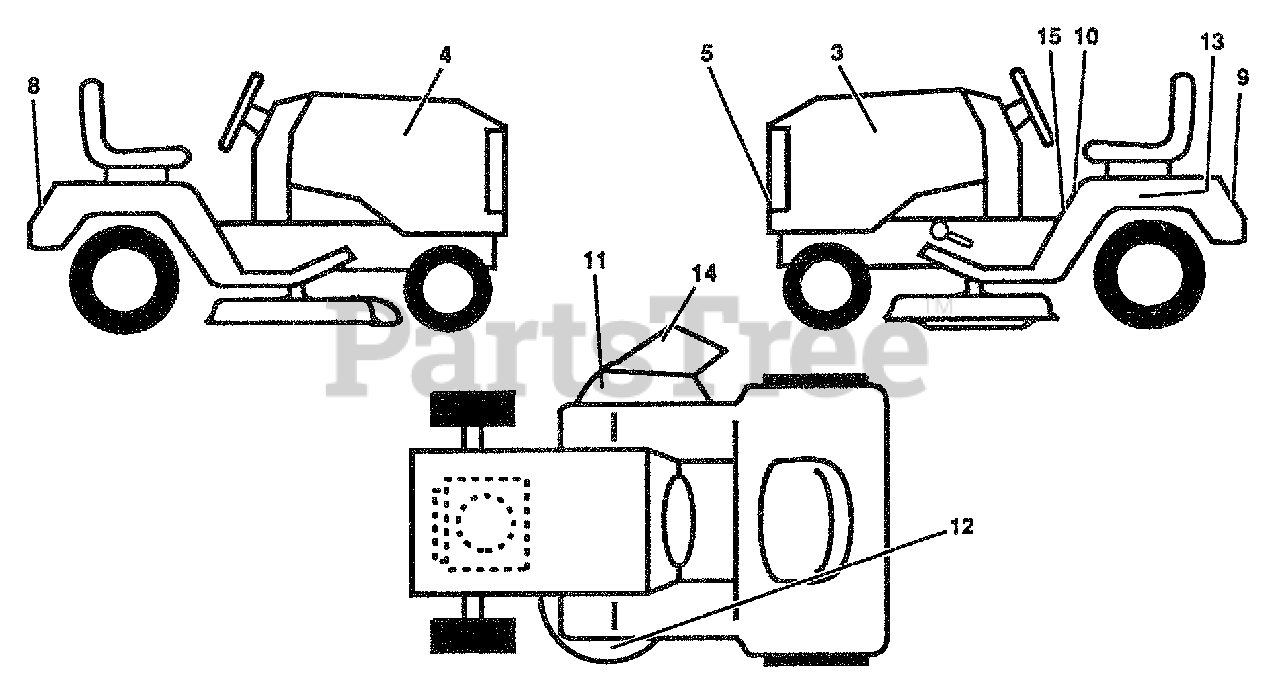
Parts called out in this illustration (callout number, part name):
3	Decal, Hood, L.H.
4	Decal, Hood, R.H.
5	Decal, Logo, Grill
8	Decal, Logo, Fender
10	Decal Caution Fender
11	Decal, Warning, Cut Finger, (Swedish/Danish/Finnish/Norwegian)
11	Decal, Warning, Cut Finger, (English/French/German/Dutch)
11	Decal, Warning, Cut Finger, (Spanish/Italian)
12	Decal, Rotating Blades, (Swedish/Danish/Finnish/Norwegian)
12	Decal, Rotating Blades, (English/French/Germany/Dutch)
12	Decal, Rotating Blades, (Spanish/Italian)
13	Decal, Caution, Battery
14	Decal, Caution, Deflector, (Swedish/Danish/Finnish/Norwegian)
14	Decal, Caution, Deflector, (English/French/German/Dutch)
14	Decal, Caution, Deflector, (Spanish/Italian)
15	Decal, Instruction, Warning, (Swedish/Danish/Finnish/Norwegian)
